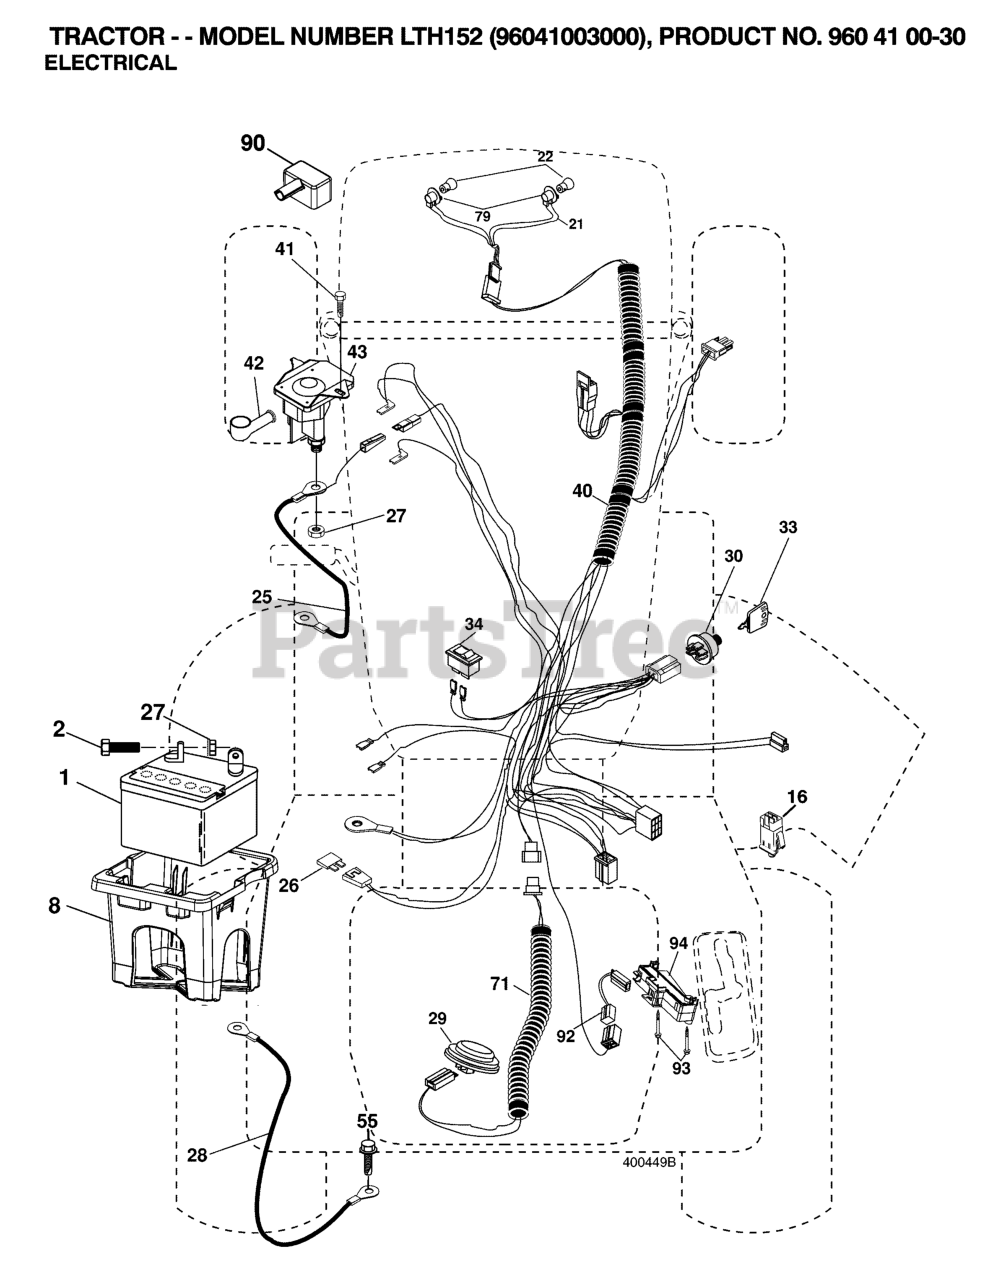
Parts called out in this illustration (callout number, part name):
1	BATTERY 12V .35 AMP
2	BOLT.HEX.1/4.X.3/4.DICHROMATE
8	BOX.BATTERY.MNT.REAR.L
16	SWITCH INTERLOOK PUSH-IN
21	HARNESS.LIGHT W/4152J BULBS
25	CABLE.STARTER.6GA.RED.
26	FUSE 20AMP
27	NUT
28	CABLE.BLACK.18"REAR.BA
29	SWITCH.SEAT.DP W/RAMPS
30	SWITCH.IGN.DELTA.W.LGH.ROS
33	KEY MLD GEN DELTA
40	HARNESS IGN. DASH
41	SCREW
42	TERMINAL COVER
43	SOLENOID.W/BRASS.PLUNGER
55	SCREW 5/16"
71	HARNESS.IGN.CHASS.TEX.REAR.BAT
79	BULB HOLDER ASM.
90	COVER, TERMINAL BATTERY
92	HARNESS.PIGTAIL.CONSLE
93	SCREW.PLASTITE
94	MODULE.REVERSE.ROS
